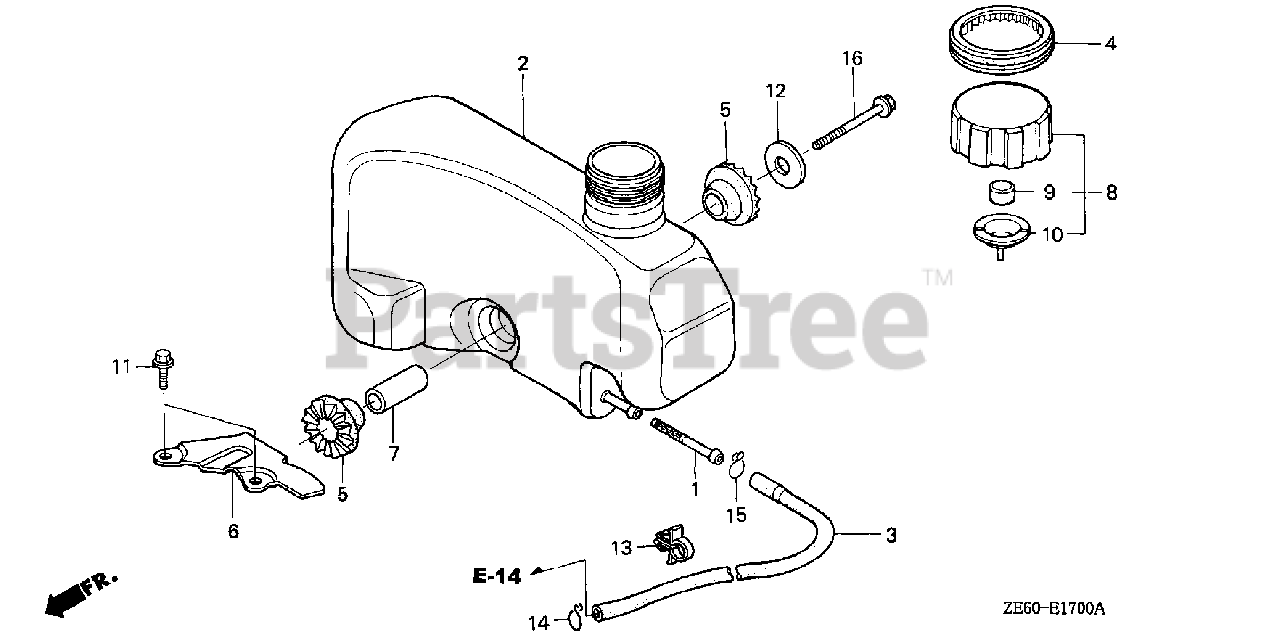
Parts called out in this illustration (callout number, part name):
1	FILTER, FUEL
2	TANK, FUEL
3	TUBE, FUEL
4	RUBBER, TANK MOUNTING
5	RUBBER B, TANK MOUNTING
6	STAY, TANK
7	COLLAR, TANK SETTING
8	CAP ASSY., FUEL TANK
9	SPONGE, FUEL CAP BREATHER
10	GASKET, FUEL CAP
11	BOLT, FLANGE (6X14) (CT200)
12	WASHER, TANK MOUNTING
13	CLIP B, CABLE (9MM BLACK)
14	CLIP, TUBE (B8)
15	CLIP, TUBE (C11)
16	BOLT, FLANGE (8X50)
